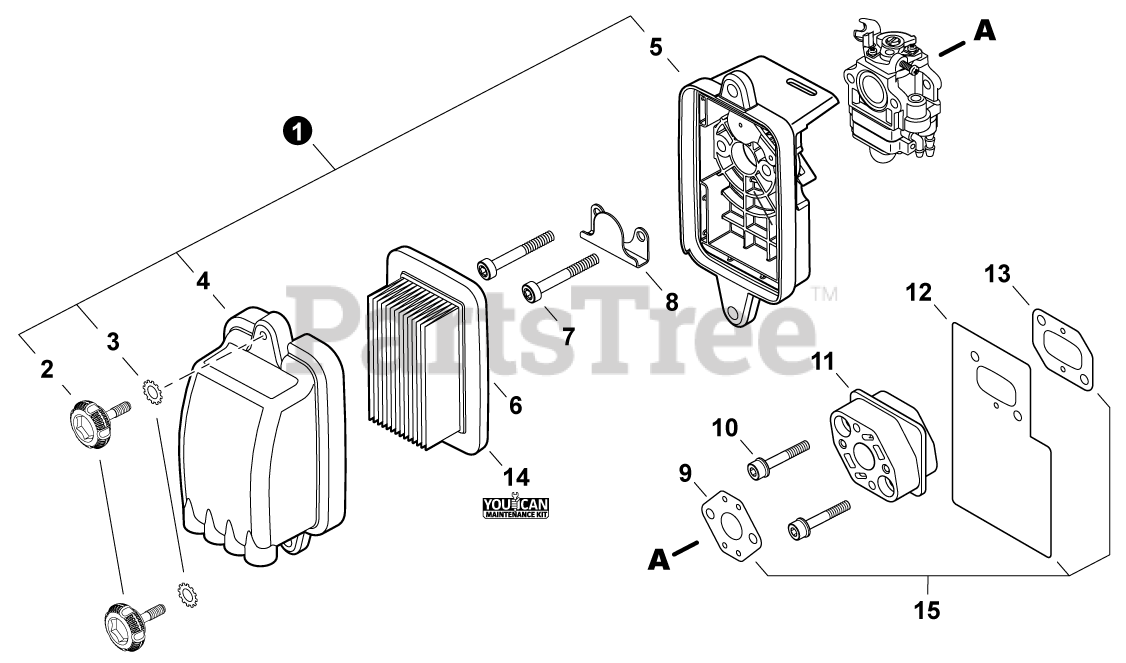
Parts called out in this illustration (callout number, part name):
1	FILTER KIT, AIR
2	THUMBSCREW
3	WASHER, LOCK
4	COVER, AIR FILTER
5	CASE ASSY, AIR FILTER
6	FILTER, AIR
7	BOLT 5x55
8	PLATE, PREVENT
9	GASKET, INTAKE
10	BOLT 5x25
11	INSULATOR, INTAKE
12	HEAT SHIELD, INTAKE
13	GASKET, INTAKE
14	TUNE-UP KIT - YOUCANT
15	GASKET KIT
